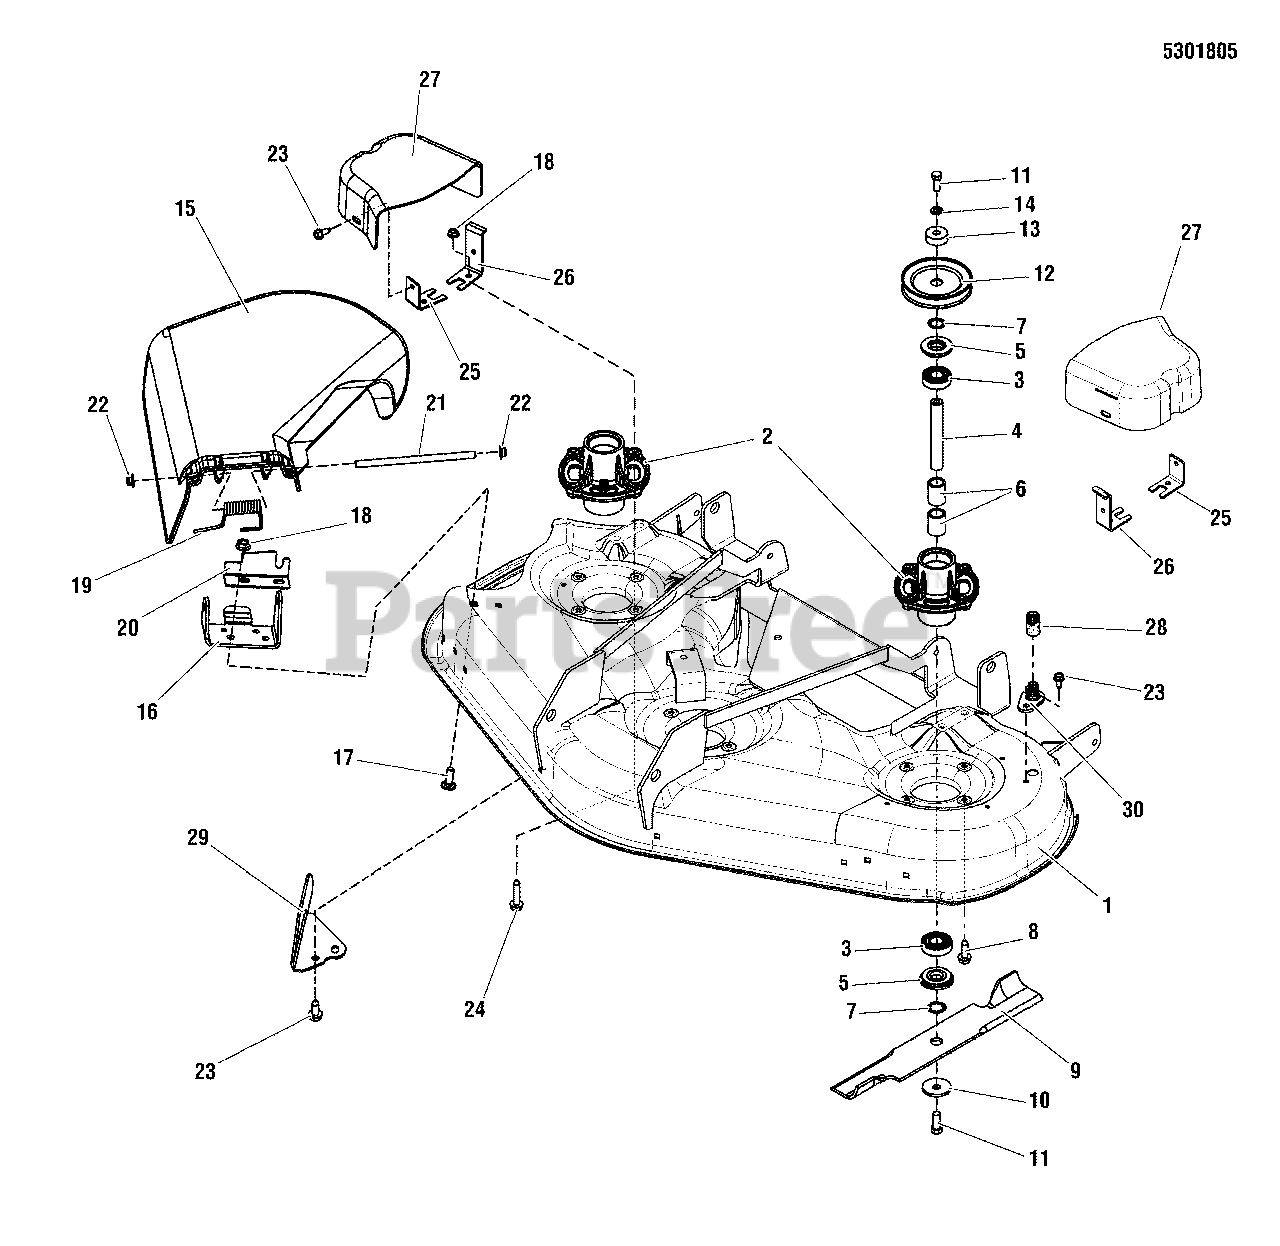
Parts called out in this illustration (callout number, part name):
1	DECK SHELL, W/ DECALS, 46, SNP 355Z
2	HOUSING, SPINDLE, CAST STEEL, MACHINED
3	BEARING, BALL, 20MM 46" MWR
4	SHAFT, SPINDLE, 20MM DIA 134.60MM LG
5	SHIELD, ARBOR, 2.050OD 46" MWR
6	SPACER, BEARING PWDR MTL 46" MWR
7	RING, SELF LOCKING 46" MWR
8	CAPSCREW, Hex Washer Head Taptite, 5/16-18X1.000BLK
9	BLADE, MOWER 16.13LG 46" MWR
10	WASHER, SPRING 0.475IDX1.75ODX.156TH BLK
11	CAPSCREW, HEX HD 7/16-14X1.000 G5 BLK
12	PULLEY, 4.6 OD 11GA SPLIT 46" MWR
13	SPACER, LOWER DRIVE 46" MWR
14	LOCKWSHER, SPRING .438 BLK
15	DEFLECTOR, DISCH PLASTIC 46/52 DECKS
16	PIVOT, HINGE
17	BOLT, RD HD SH SQ NK 5/16-18X0.750 G5 BLK
18	NUT, HEX FLANGE 5/16-18, WHIZ LK SM, YZ
19	SPRING, TORS DEFLECTOR 2.16LG 46" MWR
20	PLATE, DEFLECTOR CLOSEOFF
21	ROD, DEFLECTOR, YELLOW ZINC
22	NUT, PUSH, 5/16 BZ
23	CAPSCREW, Hex Washer Head Taptite, 5/16-18X0.750BLK
24	CAPSCREW, Hex Washer Head Taptite, 5/16-18X1.500 BLK
25	BRKT, BELT COVER, SHORT
26	BRKT, BELT COVER, TALL W/ TAB
27	COVER, BELT BLACK POLY 46 + 52" MWRS
28	CONNECTER, WASHOUT PORT, 46+52" BLK POLY
29	BAFFLE, PINCHOFF
30	ADAPTER, WASHOUT PORT 46+52" PLASTIC
